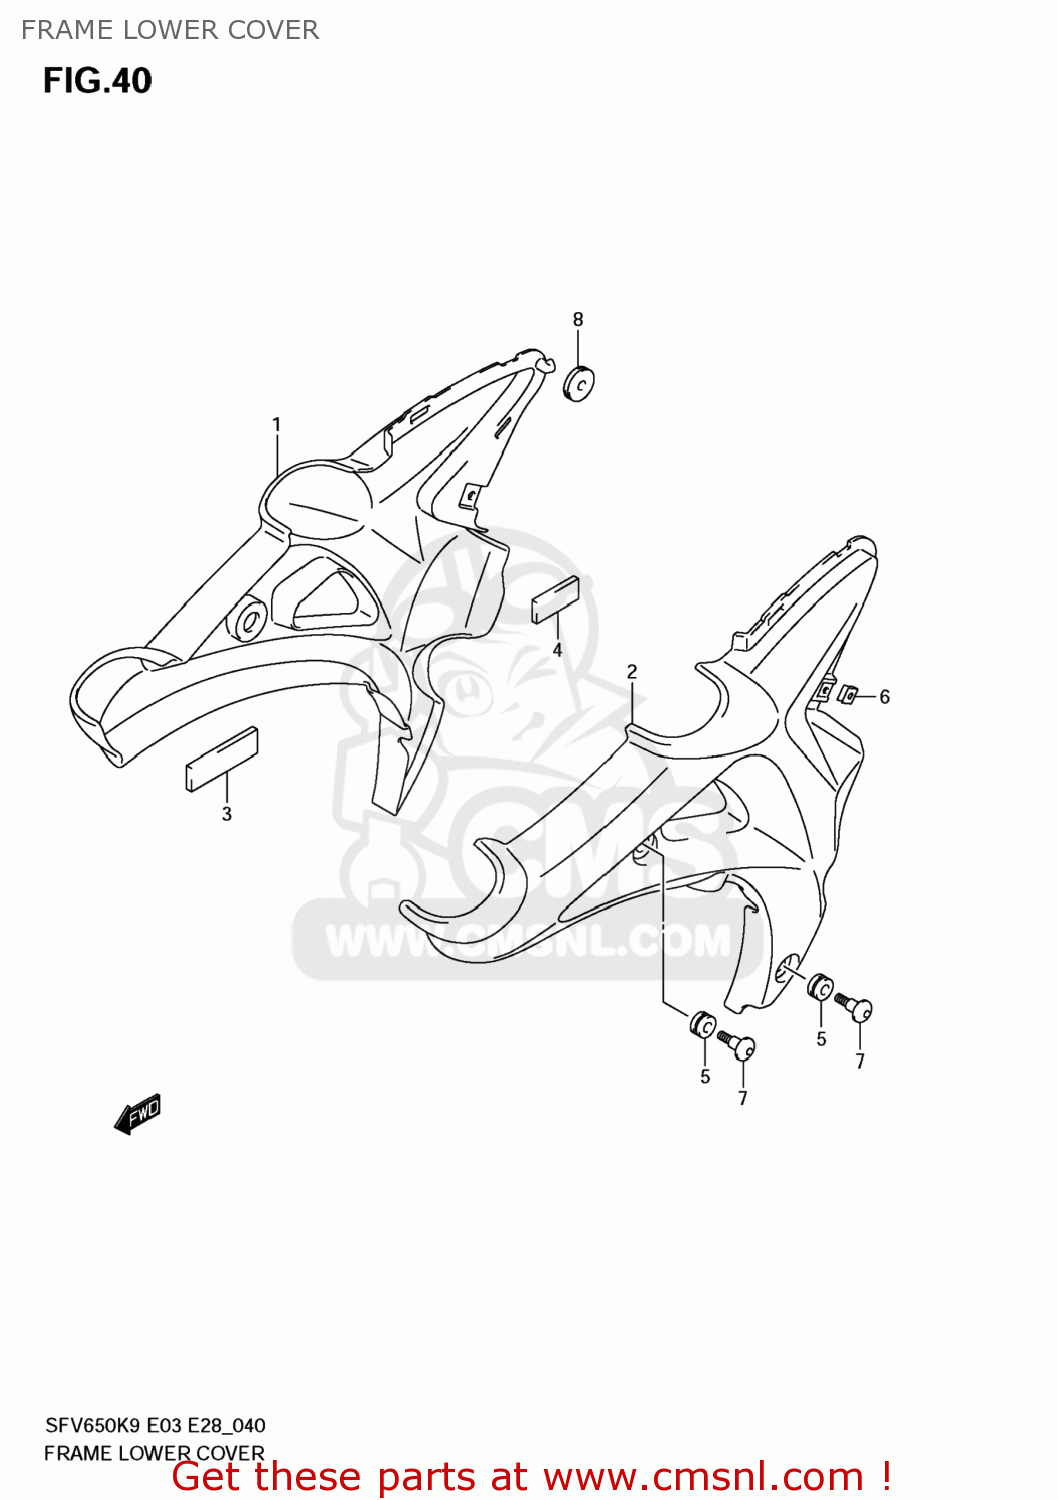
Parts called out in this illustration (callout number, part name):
1	COVER,FRAME LWR,R
2	COVER,FRAME LWR,L
3	CUSHION,FRAME COVER LWR NO.1
4	CUSHION,FRAME COVER LWR NO.2
5	CUSHION
6	NUT
7	SCREW(6X20)
8	CUSHION
